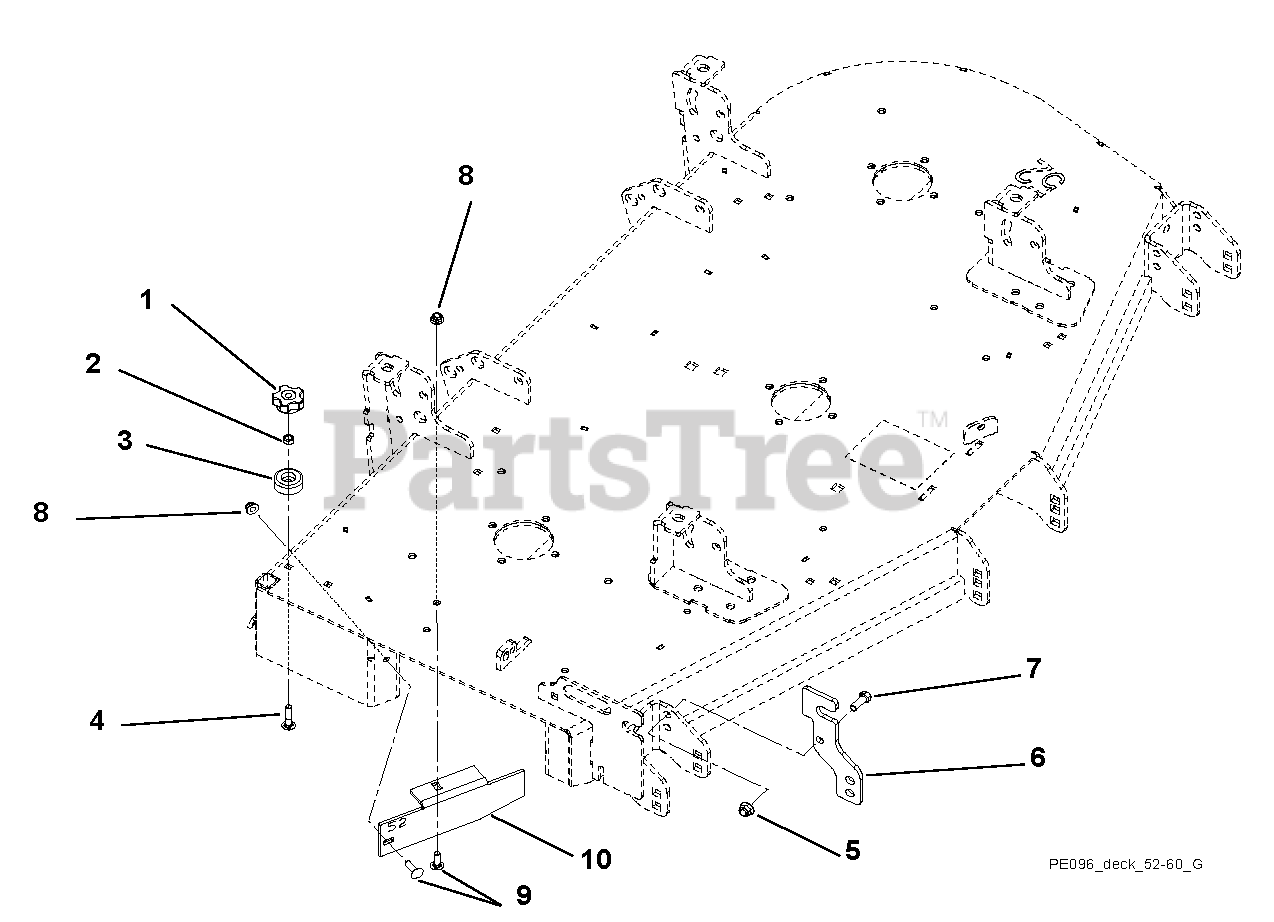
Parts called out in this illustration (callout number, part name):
1	Knob, Clamping, .312-18 Nyloc
2	Nut, Locking Center .31-18
3	Bumper, Recessed 1.50 x .63 w/.31 Thru Hole
4	Bolt, Round Head Square Neck .31-18 x 1.50
5	Nut, .38-16 Nyloc Flange
6	Chute Storage Bracket
7	Bolt, Hex .38-16 x 1.00
8	Nut, Locking Nyloc Flange .31-18
9	Bolt, Round Head Square Neck .31-18 x 1.00
10	Discharge Baffle (991080, 096, 103)
